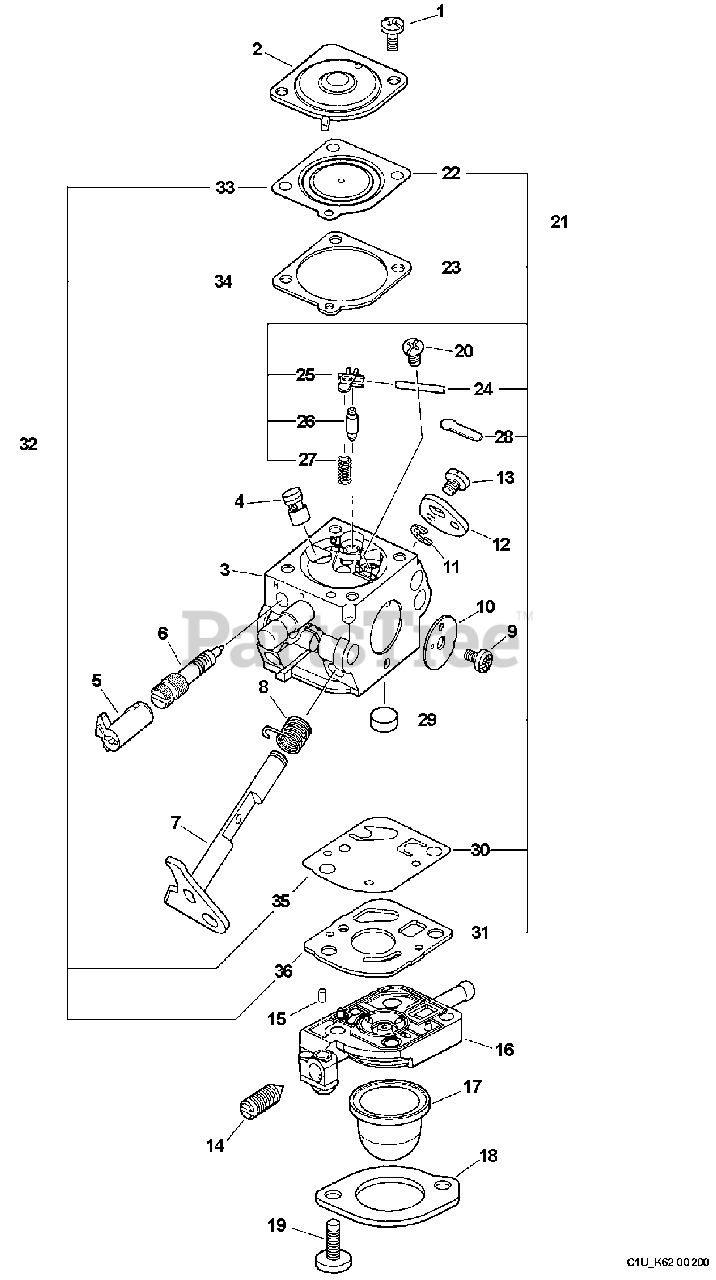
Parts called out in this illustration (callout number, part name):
2	COVER, METERING
3	BODY, CARBURETOR
4	NOZZLE, CHECK VALVE
5	CAP, LIMITER
6	NEEDLE - HIGH SPEED
7	SHAFT, THROTTLE
8	SPRING, TRIGGER
10	VALVE, THROTTLE
11	RING, RETAINING
12	LEVER, THROTTLE
14	SCREW, IDLE ADJUST
15	PIECE, FRICTION
16	BASE, PURGE
17	BULB, PURGE
18	RETAINER, PURGE BULB
19	SCREW, RETAINER
20	SCREW, METERING LEVER PIN
21	REPAIR KIT
22	DIAPHRAGM, METERING
23	GASKET, DIAPHRAGM
24	PIN, METERING LEVER
25	LEVER, METERING
26	VALVE, INLET NEEDLE
27	SPRING, METERING LEVER
28	PLUG, WELCH
29	STRAINER
30	DIAPHRAGM, PUMP
31	GASKET, PUMP
32	DIAPHRAGM/GASKET KIT
33	DIAPHRAGM, METERING
34	GASKET, DIAPHRAGM
35	DIAPHRAGM, PUMP
36	GASKET, PUMP
